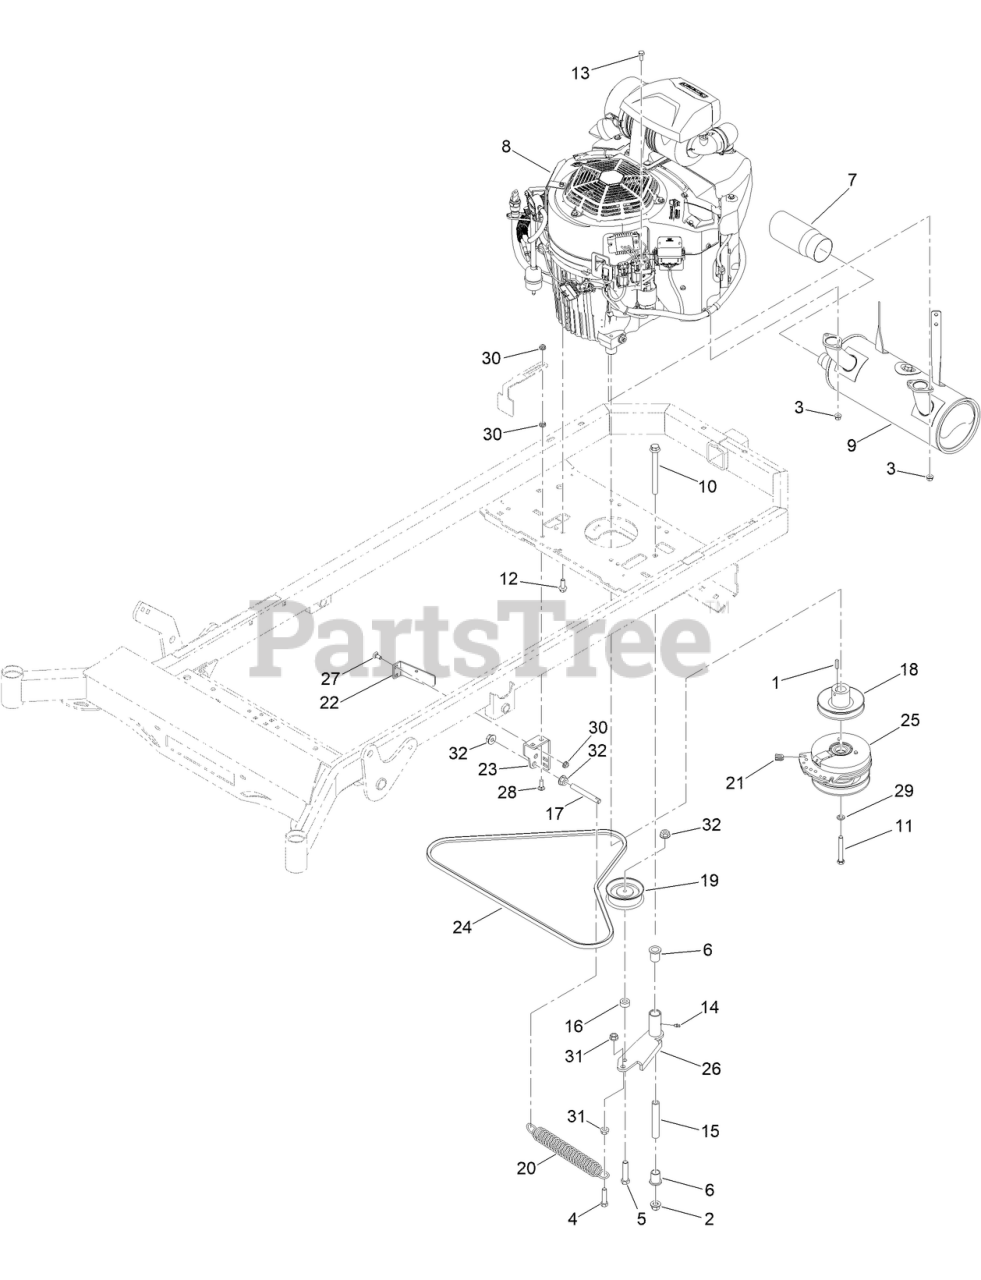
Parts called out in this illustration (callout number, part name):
2	NUT-LOCK
3	NUT-HF
4	SCREW-HH
5	SCREW-HH
6	3/4IN ID X15/16IN OD X 1-1/8IN FLNG BUSH
7	MWR CHROME EXHAUST TIP
8	KAWASAKI FXT1000V-EFI ENGN
9	MUFFLER W/ ARRESTER-6INOD-1.5INTP
10	1/2-13 X 5-1/2 HEX FLANGE BOLT GR 8 ZY
11	7/16-20 X 3 HEX C/S GR 8 ZC YELLOW
12	3/8-16 X 1-1/8 IND HWH W/SERR TRI LOB ZY
13	M8-1.25 X 20MM HEX FLANGE BOLT ZINC 10.9
14	1/4IN DRIVE TYPE GREASE FITTING YZ
15	MWR INNER IDLER SPACER
16	MWR PULLEY SPACER
17	MWR PUMP IDLER SPRING TENSIONER
18	MWR HYDRAULIC PUMP DRIVE PULLEY (B-BELT)
19	4IN DIESEL AND ECONOMY MWER IDLER PULLEY
20	MWR DECK SPRING
21	MWR CLUTCH ROTATION STOP BRKT SLEEVE
22	MWR CLUTCH ANTI ROTATION BRKT PAINTED
23	MWR PUMP IDLER TENSIONING BRKTPAINTED
24	MWR PUMP BELT XD B X 69.40IN EFF LNGTH
25	WARNER PTO CLUTCH
26	4IN PUMP IDLER PULLEY ARM ASSY PAINT
27	BOLT-CARR
28	BOLT-CARR
29	WASHER-LOCK
31	NUT-HF
32	NUT-HHF
